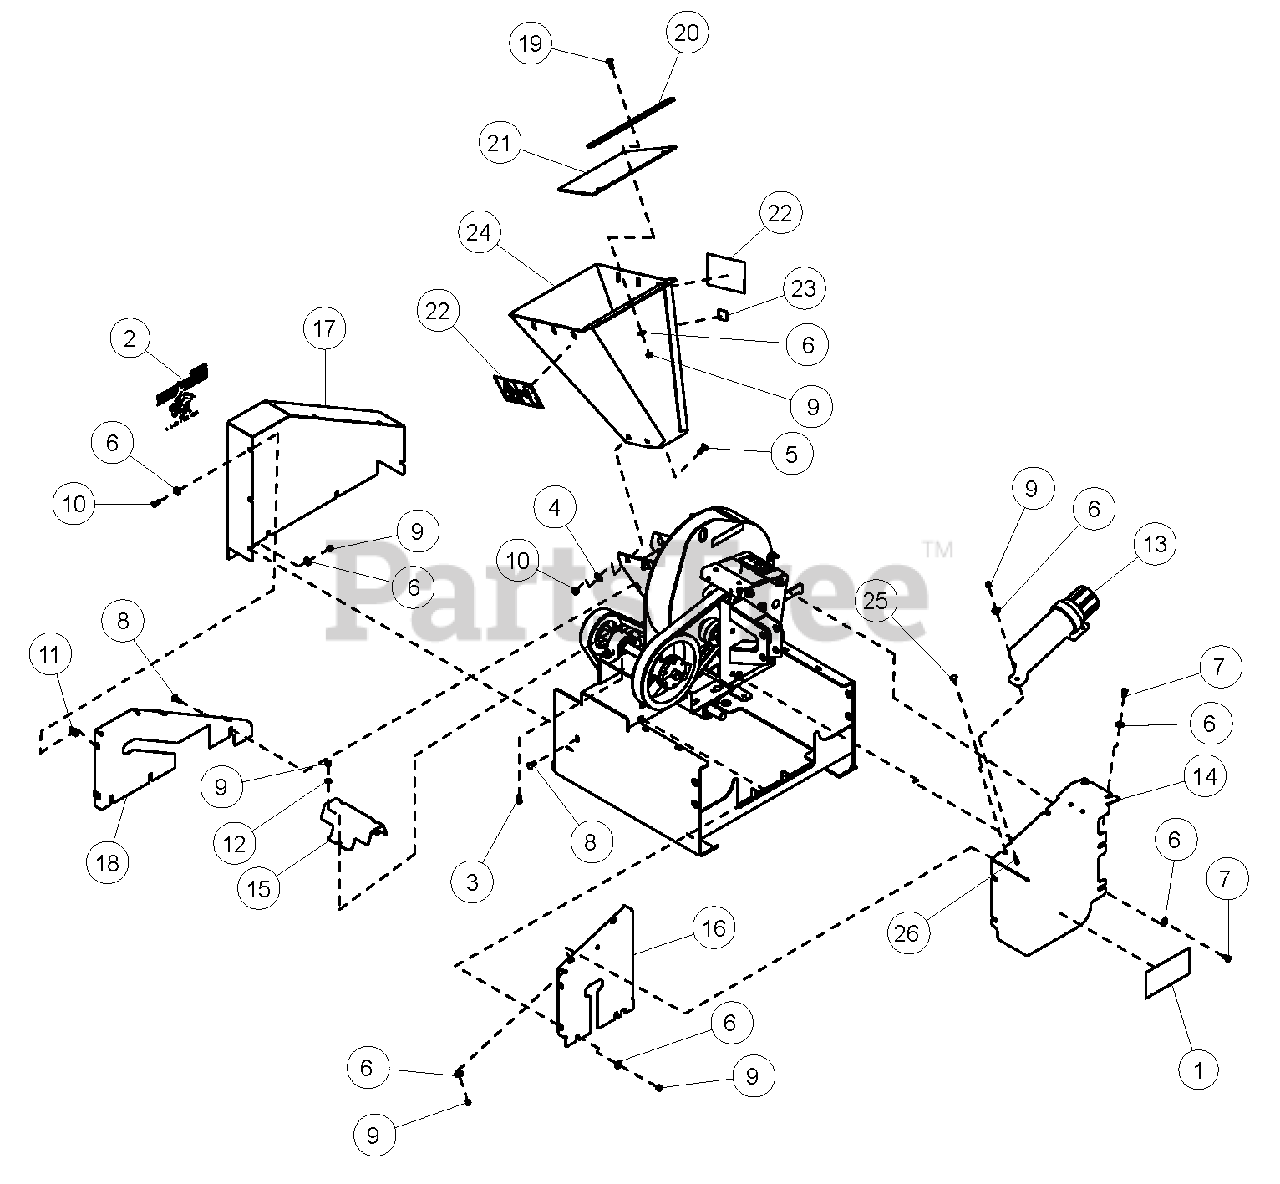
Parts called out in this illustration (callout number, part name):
1	DECAL, PTO DANGER
2	DECAL, ECHO LOGO
2	DECAL, CRARY LOGO
3	BOLT, 5/16 X 3/4" HEX HD
4	WASHER, 3/8" FLAT
5	BOLT, 3/8 X 1" CRG
6	WASHER, 5/16" FLAT
7	BOLT, 5/16 X 5/8" HEX HD
8	BOLT, 5/16 X 7/8" CRG
9	NUT, 5/16" NYLOCK
10	NUT, 3/8" NYLOCK
11	NUT, 5/16" X 18 TINNERMAN U-TYPE
12	WASHER, 5/16" SAE FLAT
13	CONTAINER, MANUAL
14	SHIELD, FRONT BELT
15	SHIELD, JACKSHAFT
16	SHIELD, BACK BELT
17	SHIELD, FORWARD BELT
18	SHIELD, REAR BELT
19	BOLT, 5/16 X 1" GR5 CRG ZP
20	STRIP, FLAP RETAINER
21	FLAP, CHIPPER CHUTE
22	DECAL, INLET AND DISCHARGE
23	DECAL, CE APPROVAL
24	WELDMENT, HOPPER
25	BOLT, 5/16 X 3/4" GR5 ZP CRG
26	BOLT, 5/16 X 7/8" NC HHCS GR5 ZP
